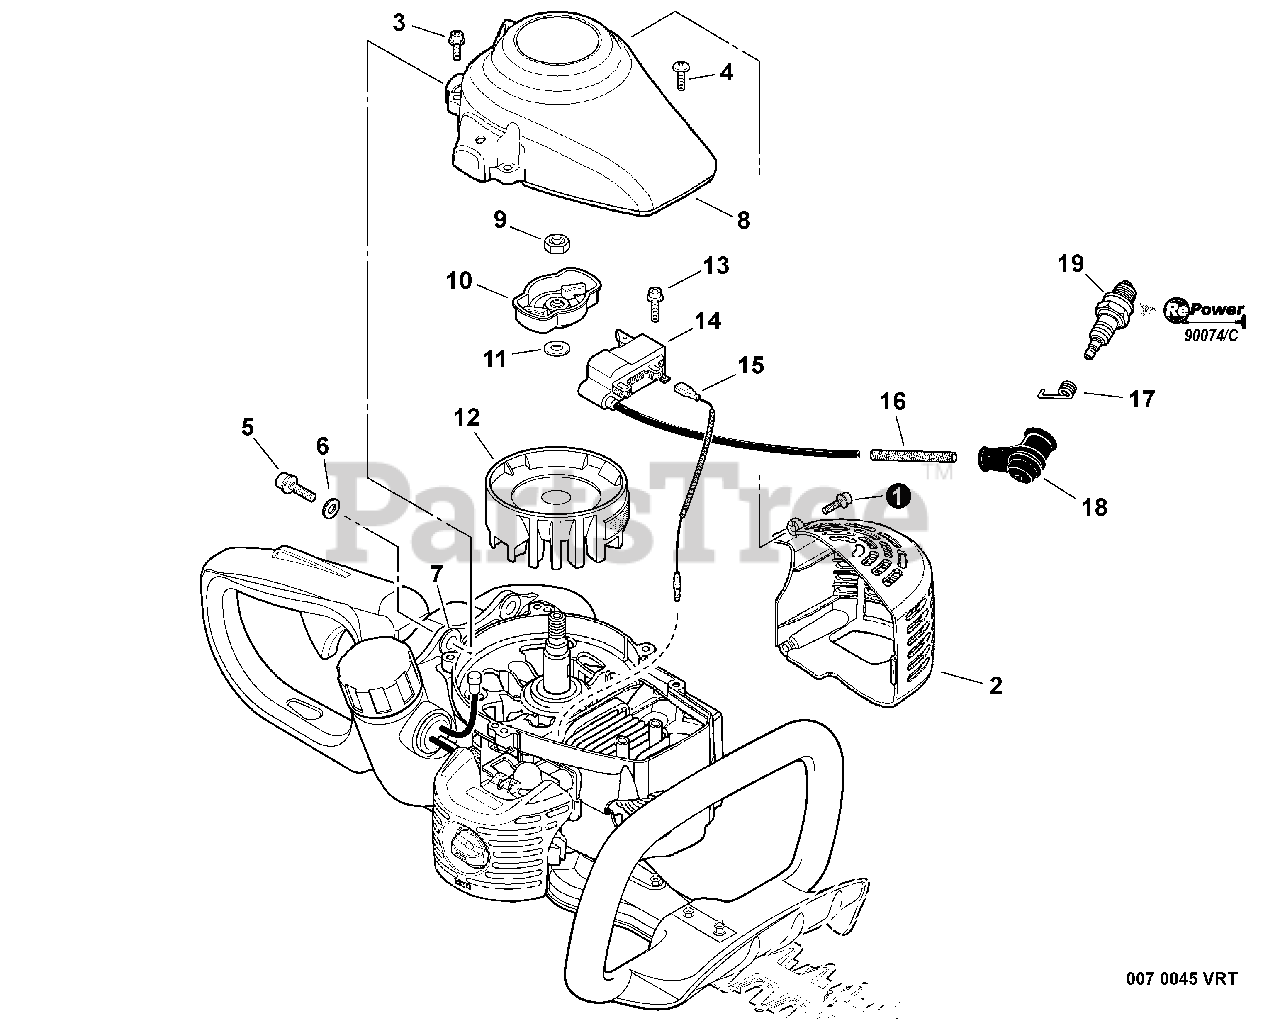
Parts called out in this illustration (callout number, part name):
1	BOLT 5×16
2	COVER, MUFFLER
3	BOLT 4×16
4	BOLT 4×12
5	BOLT 5×20
6	WASHER 5.5×12×0.8
7	COLLAR 5
8	STARTER ASSY, RECOIL
10	PULLEY ASSY, STARTER
11	WASHER 8.5×16×1.2
12	FLYWHEEL
13	BOLT 4×20
14	COIL, IGNITION
15	LEAD - IGNITION
16	TUBE, INSULATOR 7×8.6×55
17	TERMINAL, SPARK PLUG
18	CAP, SPARK PLUG
19	SPARK PLUG - BPM8Y
19	SPARK PLUG - BPMR8Y
20	TUNE-UP KIT - REPOWER
